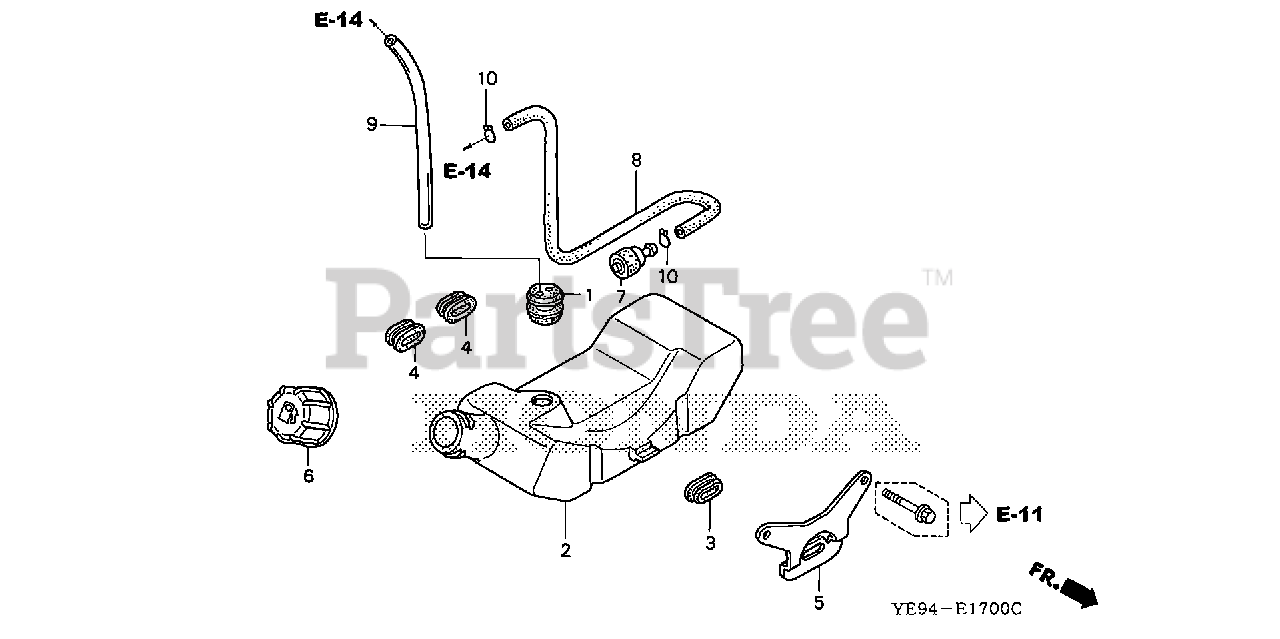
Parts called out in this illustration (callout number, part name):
1	GROMMET, FUEL TUBE
2	TANK, FUEL
3	RUBBER A, TANK MOUNTING
4	RUBBER A, TANK MOUNTING
5	STAY, FUEL TANK
6	CAP ASSY., FUEL TANK
7	FILTER, FUEL
8	TUBE, FUEL
9	TUBE, FUEL RETURN
10	CLIP, TUBE
